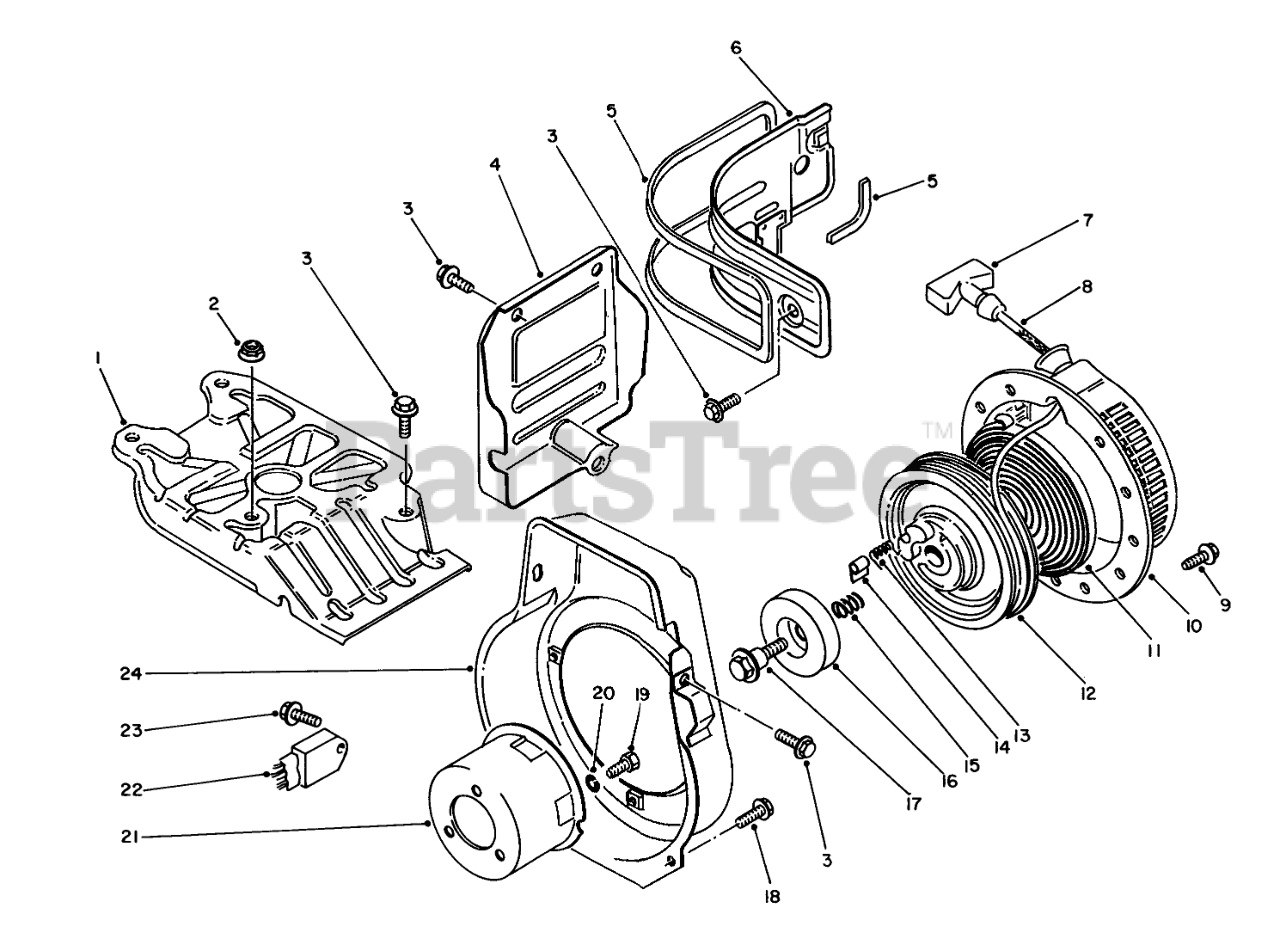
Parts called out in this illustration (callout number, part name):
1	Cowling-Upper
4	Cover-Unit
6	Cowling-Ventilation Side
7	Grip
8	Grip Assembly (Incl. Ref. #7)
10	Starter Assembly-Recoil (Incl. Ref. #10-17)
11	SPRING
13	SPRING
15	SPRING
16	RETAINER
19	Screw
20	Washer-Lock
21	Pulley
22	Unit-Oil Level Alarm
24	Cover-Cooling Fan
